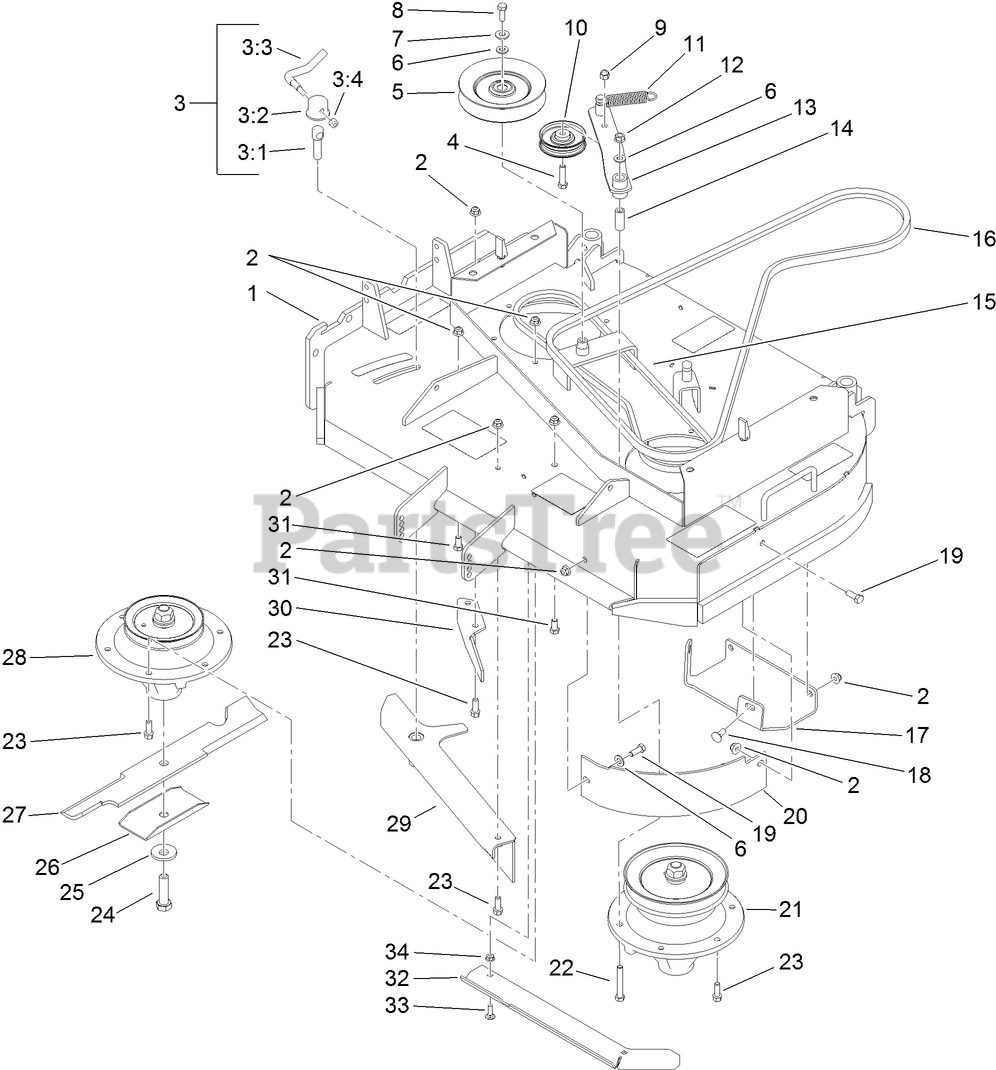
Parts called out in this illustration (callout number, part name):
1	DECK AND DECAL ASM
2	NUT-HF, NI
3	LEVER ASM
3:1	Screw-Lock
3:2	CAP-LOCK
3:3	Lever-Lock
3:4	NUT-LOCK, NI
4	SCREW-HH
5	PULLEY-IDLER
6	WASHER-FLAT
7	WASHER-BELLEVILLE
8	SCREW-HH
9	NUT-LOCK, NI
10	PULLEY-IDLER
11	SPRING-EXTENSION
12	NUT-HF
13	IDLER ARM ASM
14	SLEEVE-PIVOT, IDLER
15	BELT-V
16	BELT-DRIVE, PTO
17	PLATE-SKID
18	BOLT-CARR
19	SCREW-HH
20	BAFFLE-FRONT, LH
21	SPINDLE ASM
22	SCREW-HH
23	SCREW-HWH
24	SCREW-BLADE
25	Washer-Blade Bolt, Heavy
26	STIFFENER-BLADE
27	BLADE-18IN, HI FLOW
28	SPINDLE ASM
29	ADJUST BAFFLE ASM
30	BAFFLE-DISCHARGE
31	SCREW-HH
32	EXTENDER-DECK
33	BOLT-CARR
34	NUT-HF, NI
